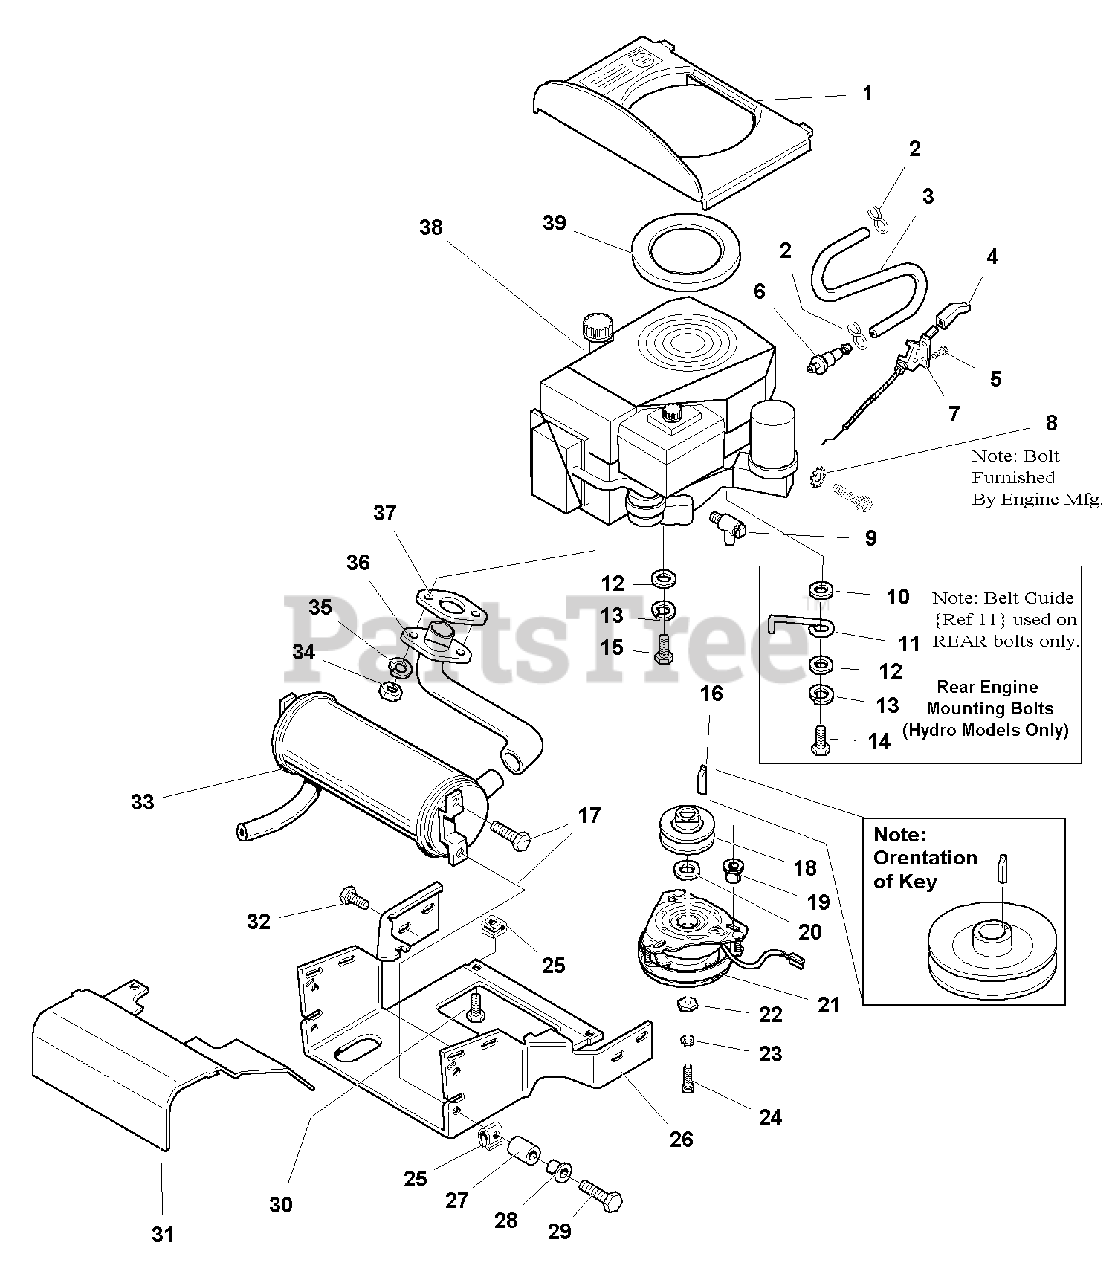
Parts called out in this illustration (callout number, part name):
1	PLENUM, Inlet
3	FUEL LINE, 45"
4	KNOB, Throttle
5	CAPSCREW, Plastite Hex Washer Head, 1/4-10 x 5/8
6	FUEL FILTER
7	CONTROL, Throttle
8	LOCKWASHER, External Tooth, 3/8
9	DRAIN VALVE, Oil
10	WASHER, 7/16
11	GUIDE, Belt
12	WASHER, 5/16
13	LOCKWASHER, 5/16
14	CAPSCREW, Hex Head, M8 1-1/4 x 40M
15	CAPSCREW, Hex Head, M8 1-1/4 x 30M
16	KEY, Hi-Pro
17	CAPSCREW, Taptite Hex Washer Head, 1/4-20 x 5/16
18	PULLEY ASSEMBLY, Engine PTO
19	SLEEVE, Clutch Anchor
20	WASHER, 1.0
21	** ELECTRIC CLUTCH, PTO
22	WASHER, Hex
23	LOCKWASHER, 7/16
24	CAPSCREW, Hex Head, 7/16-20- x 3
25	SPEED NUT, Tinnerman Lug Type, 5/16-18
26	DUCT, Muffler, Lower
27	SPACER, Steel
28	PIVOT, Hood
29	CAPSCREW, Hex Head Whiz Lock, 5/16-18 x 1-1/4
30	CAPSCREW, Hex Head Whiz Lock, 5/16-18 x 3/4
31	DUCT, Muffler, Upper
32	CAPSCREW, Taptite Hex Washer Head, 5/16-18 x 1/2
34	NUT, Exhaust
35	LOCKWASHER, 5/16
36	PIPE, Manifold
37	GASKET, Muffler
